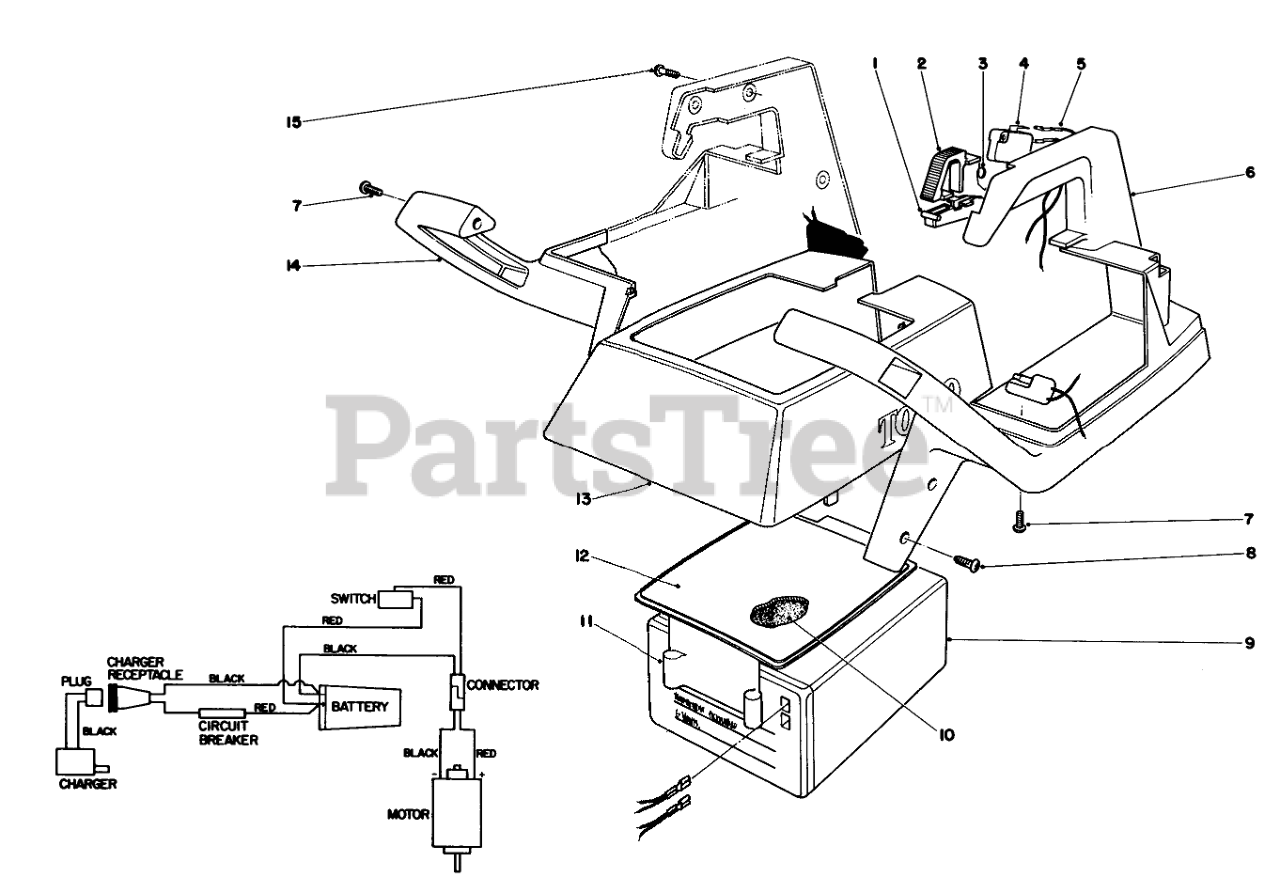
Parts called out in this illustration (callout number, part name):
1	Trigger
2	TRIGGER LOCK
3	Spring
4	Switch
5	Wiring Harness
6	LH BATTERY CASE/HNDL
7	Screw
8	10-16 X .31 SCREW
9	BATTERY
10	FOAM PAD
11	CONTROL PANEL, CL-710
12	DECAL, FRONT PANEL, CSA
13	Cover
14	RH BATTERY CASE/HNDL
15	SCREW-PPH
